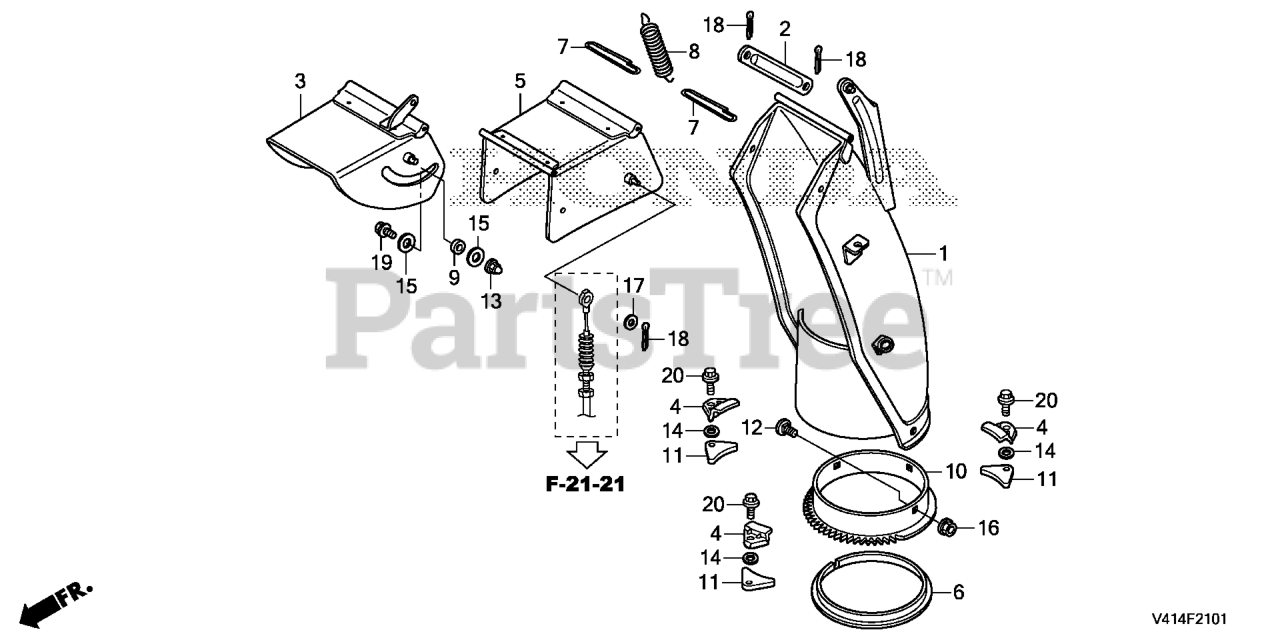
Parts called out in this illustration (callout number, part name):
1	CHUTE *R280* (POWER RED)
3	GUIDE, CHUTE
4	PLATE, CHUTE SETTING
6	BUSH, CHUTE
7	PIN, CHUTE GUIDE
8	SPRING, CHUTE (STD)
9	COLLAR, CHUTE GUIDE
10	GEAR, CHUTE
11	PLATE, MOUNTING
12	BOLT, SPECIAL (8X14)
13	NUT, CAP (6MM)
14	WASHER, CHUTE SETTING
15	WASHER (10.2X22X1)
16	NUT, FLANGE (8MM)
17	WASHER, PLAIN (6MM)
18	PIN, SPLIT
19	BOLT, FLANGE (6X12) Use up to Engine SN 1543277.
20	BOLT, FLANGE (8X16)
